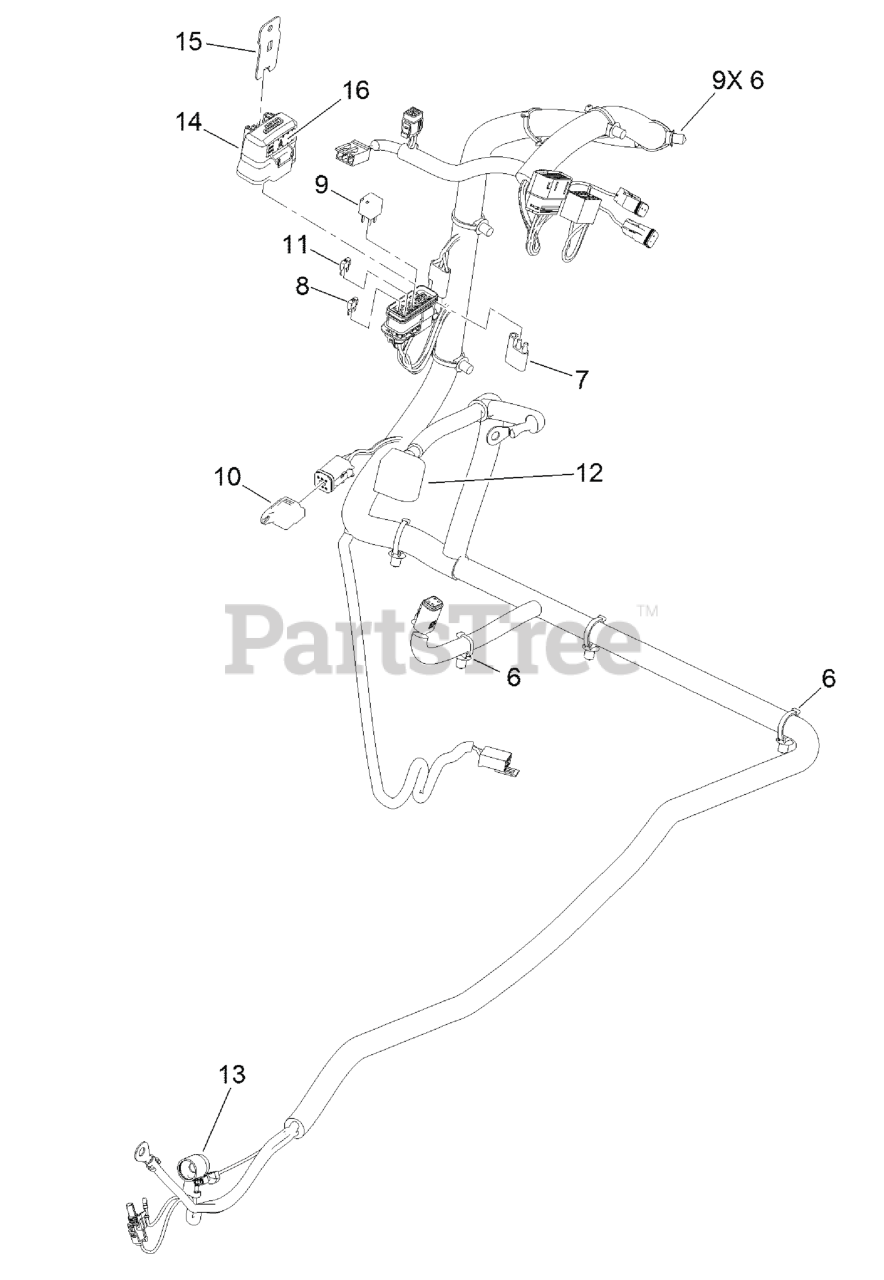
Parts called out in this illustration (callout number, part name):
6	CLIP-TIE
7	Cap-Plug
8	FUSE-MINI BLADE, 20 AMP
9	RELAY-MICRO
10	CAP-PLUG, 6 WAY
11	FUSE-MINI BLADE, 15 AMP
12	INSULATOR-BATTERY
13	INSULATOR-SOLENOID
14	COVER-BLOCK, FUSE
15	CLIP-MOUNTING
16	DECAL-FUSE
